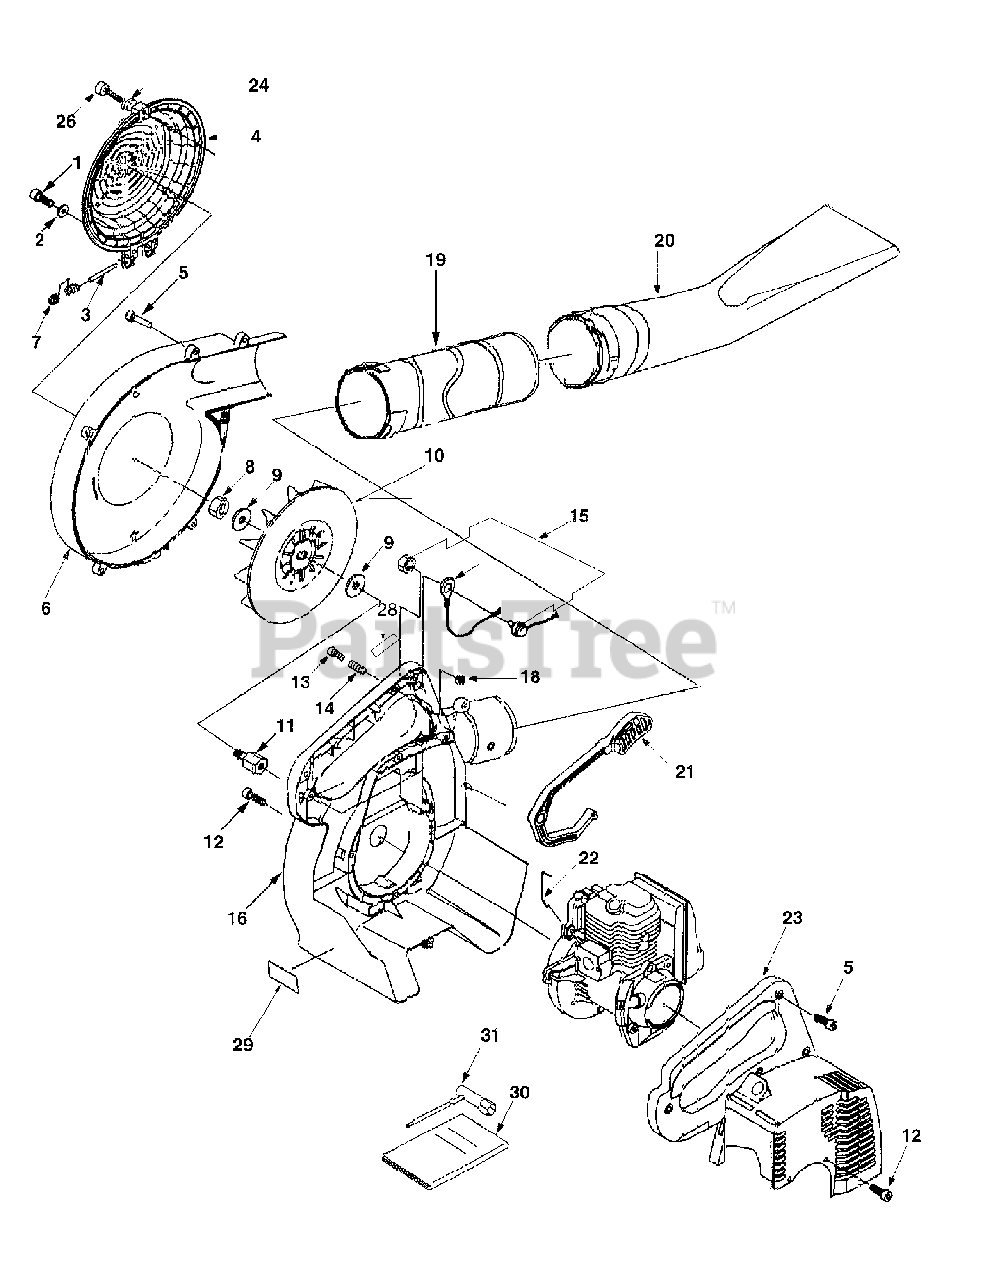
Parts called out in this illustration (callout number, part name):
1	Bolt; PC5X14
4	Guard, Fan
5	Bolt; PC5X18
12	Bolt; M5x20
13	Lever, Throttle
14	Spring, Throttle
15	Switch Compl
17	Harness, Wire
18	Snap Ring; E-3
19	Pipe, Straight
20	Pipe, Tail
21	Lever, Throttle
22	Lever, Throttle
26	Bolt; M4x30
28	Caution Plate
29	Caution Plate
30	Instruction Book
31	Wrench; 19
